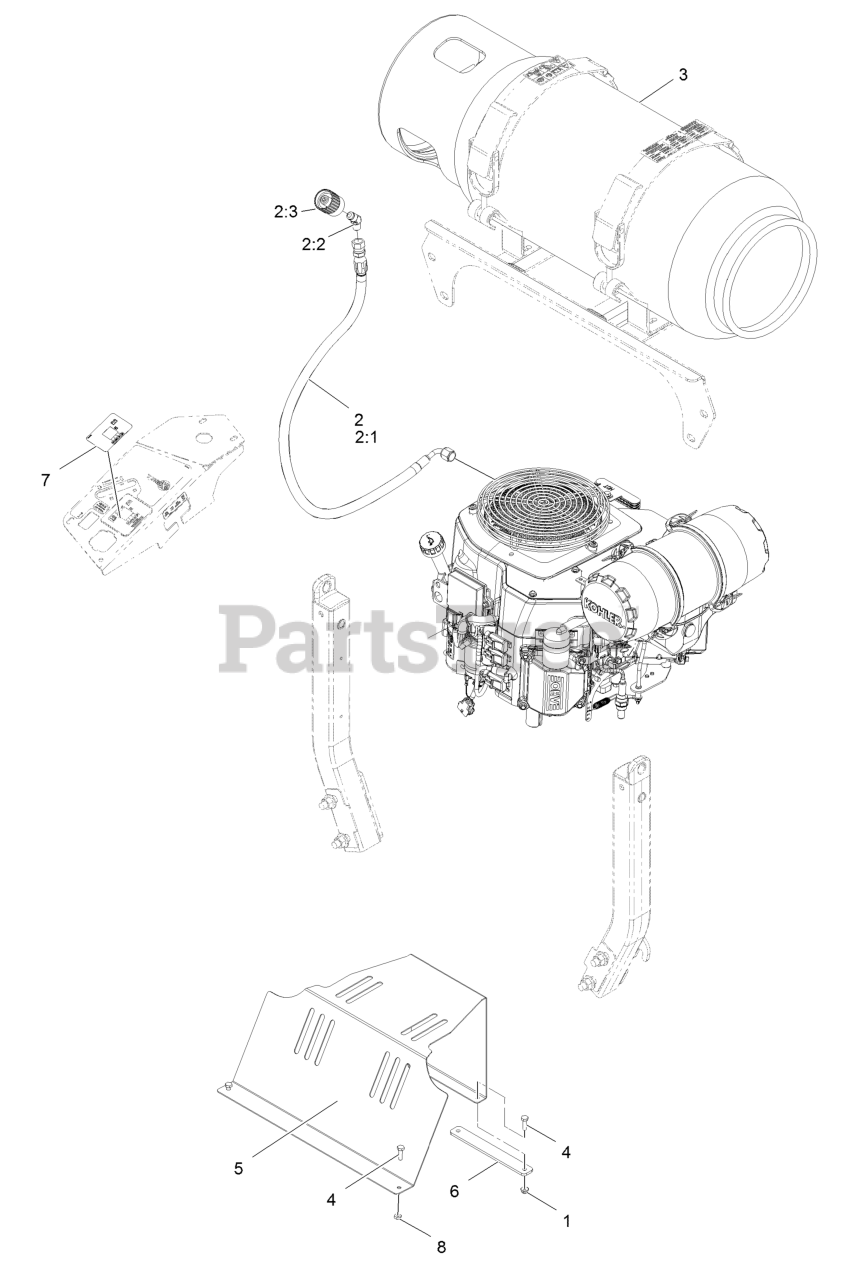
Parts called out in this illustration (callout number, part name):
2:1	LPG FUEL HOSE ASM
2:2	ELBOW-45 DEG
2:3	CONNECTOR-LPG TANK, LH TH
4	SCREW-HH
5	SHEILD-FAN
7	DECAL-METER, HOUR
8	NUT-JAM
